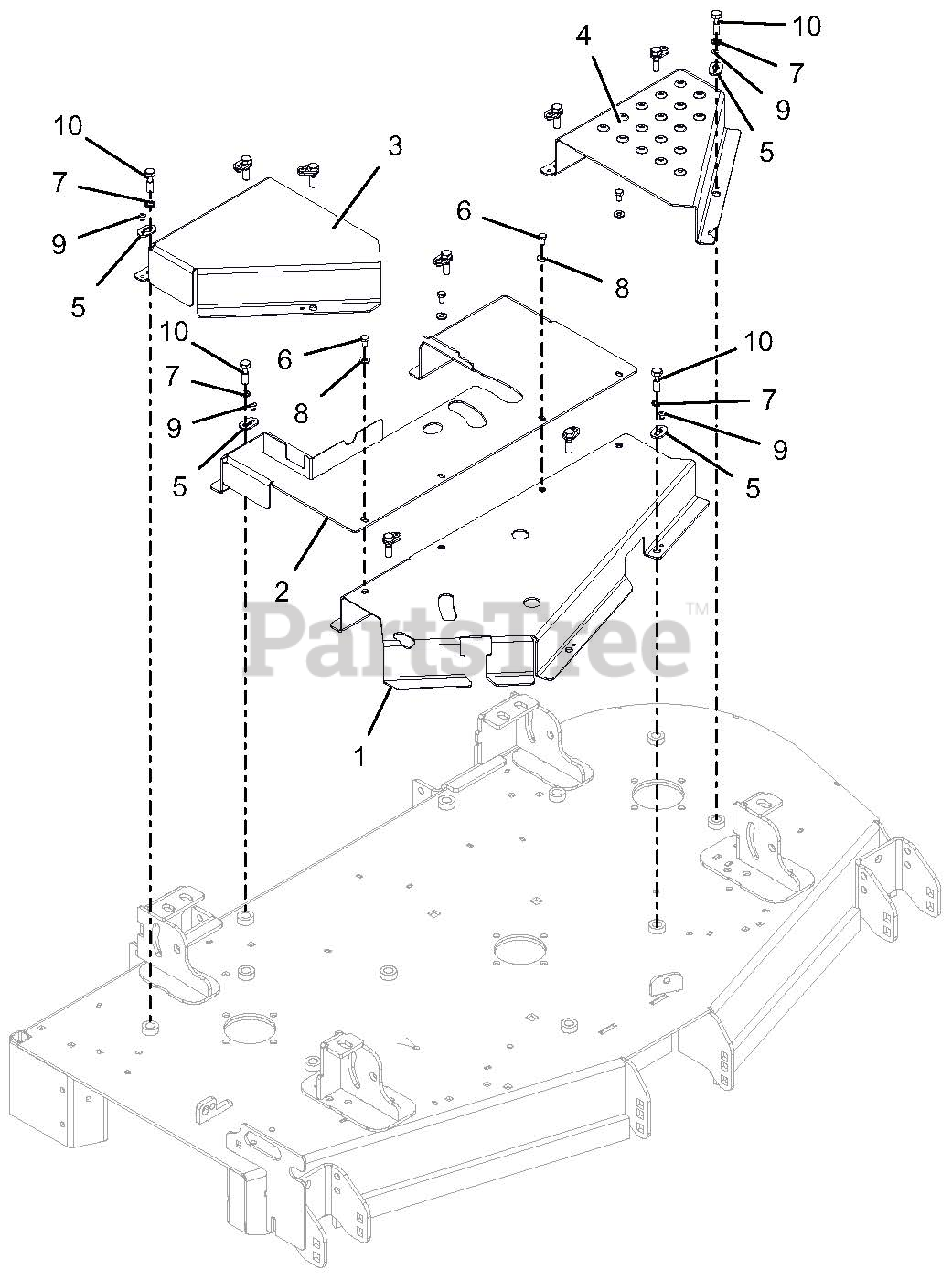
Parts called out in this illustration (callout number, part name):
1	WMT - FRONT BELT SHIELD
2	WMT,CE52"CNTR REAR DECK GRD-BK
3	GUARD, RH PT200 CE BELT (BLACK)
4	GUARD, LH PT200 CE BELT (BLACK)
5	KEEPER, BOLT
6	@BLT-HEX .25-20X.50 GR5 YWZC
7	@WSHR-LK-EXT.391X.628X.036YWZC
8	@WSHR-FL-STL.281X.62X.065 YWZC
9	RVT-POP .187x.250 (#64) YWZC
10	BLT,HEX.38-16X1.25 GR5 CAPTIVE
